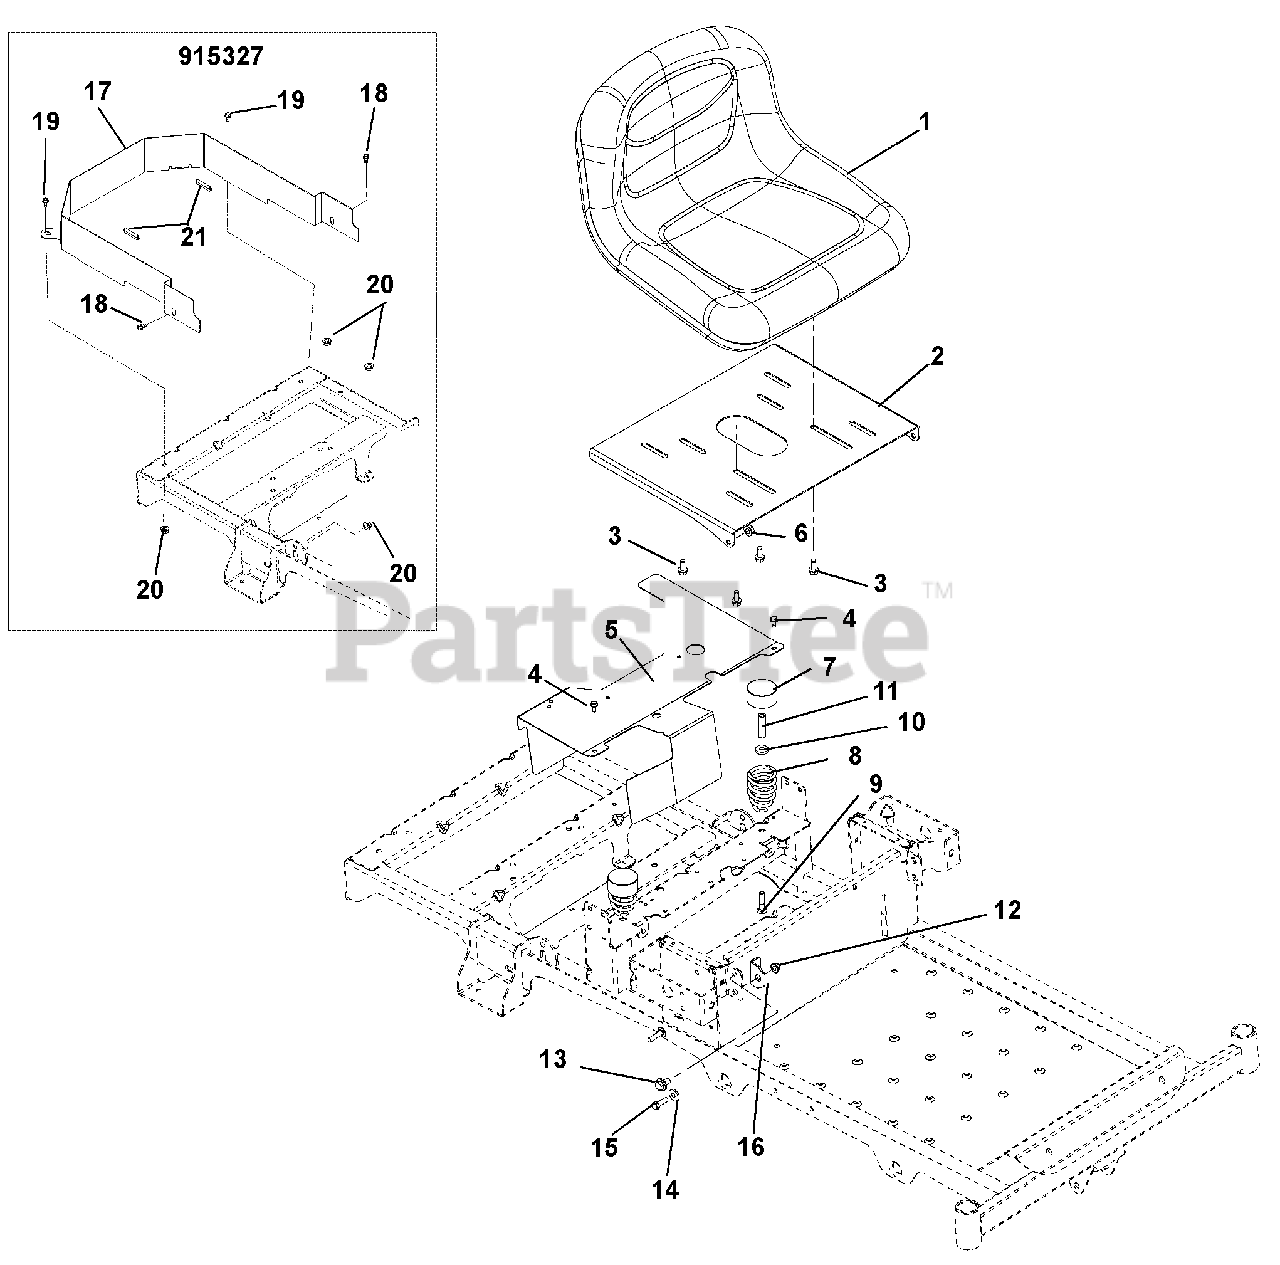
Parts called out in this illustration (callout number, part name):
1	Seat, 13 in Grey
2	Seat Plate
3	Bolt, Hex 5/16-18 x 3/4
4	Screw, Tapping .25-20 x .50 Hex Washer Head Thread
5	Cover, Zoom CE Fan
6	Nut, .38-16 Locking Top Flange
8	Spring, Seat
9	Bolt, Round Head Square Neck .31-18 x 1.50
10	Washer, Flat Steel .328 x .87 x .179
11	Nut, Coupling 5/16-18 x 1.75
12	Nut, 5/16-18 Flange Nyloc
13	Bolt, Shoulder .375-16 x .135
14	Bushing, Flange .325 x .499 x .26 x .88
15	Bolt, Hex .31-18 x 1.00
16	Bracket, Seat Stop
17	Shield, ZT CE Reach-In
18	Bolt, Hex .38-16 x .75 Grade 5 YWCZ
19	Bolt, Hex .38-16 x 1.00 Grade 5 YWZC
20	Nut, Locking Center .38-16
21	Edging, Molded
